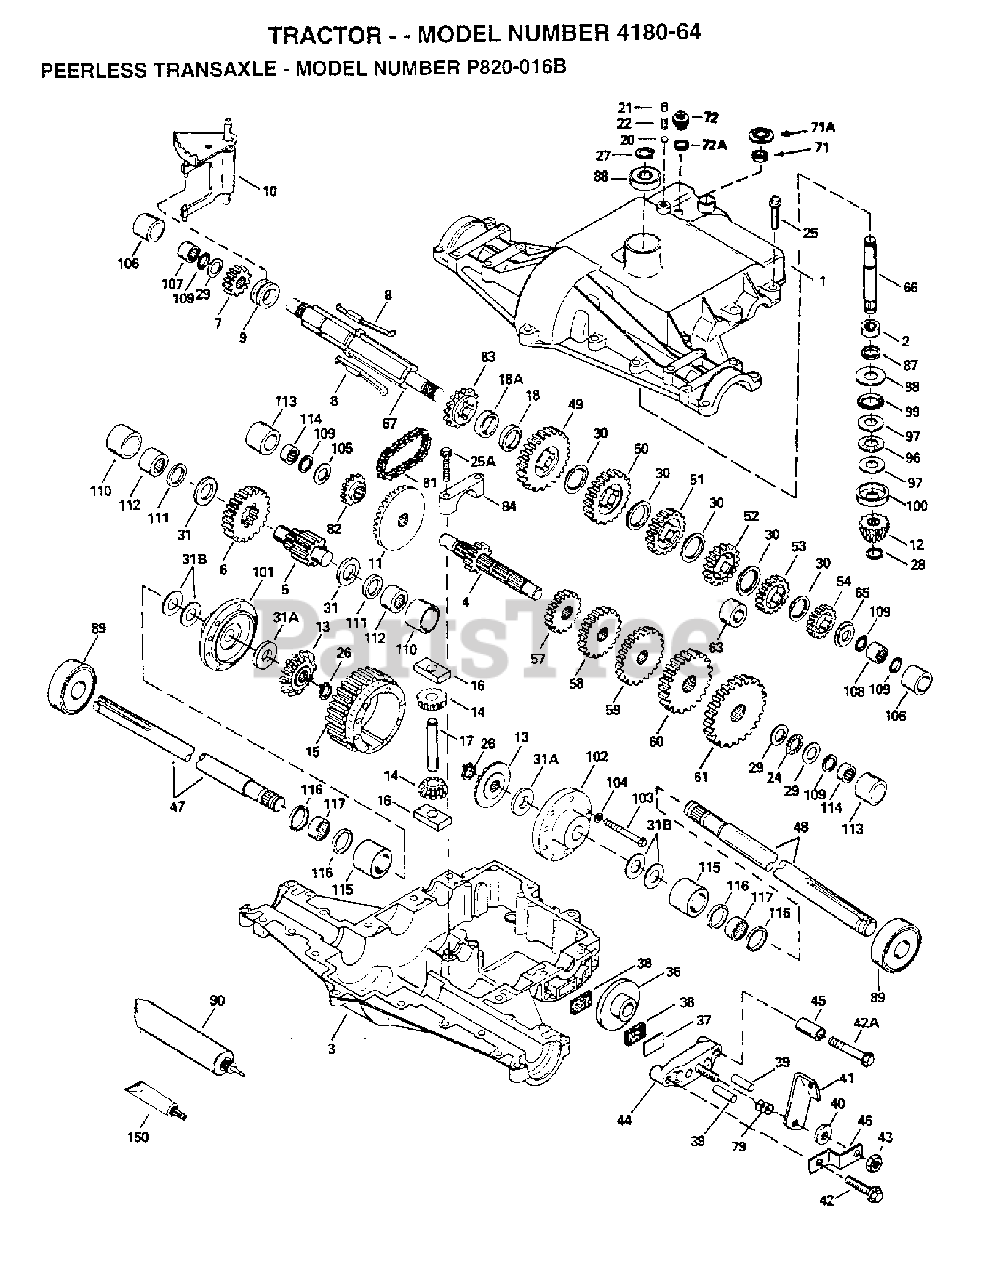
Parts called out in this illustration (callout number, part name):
1	Poulan TBD
49	Poulan TBD
50	Poulan TBD
51	Poulan TBD
53	Poulan TBD
90	Poulan TBD
114	Oil Seal
